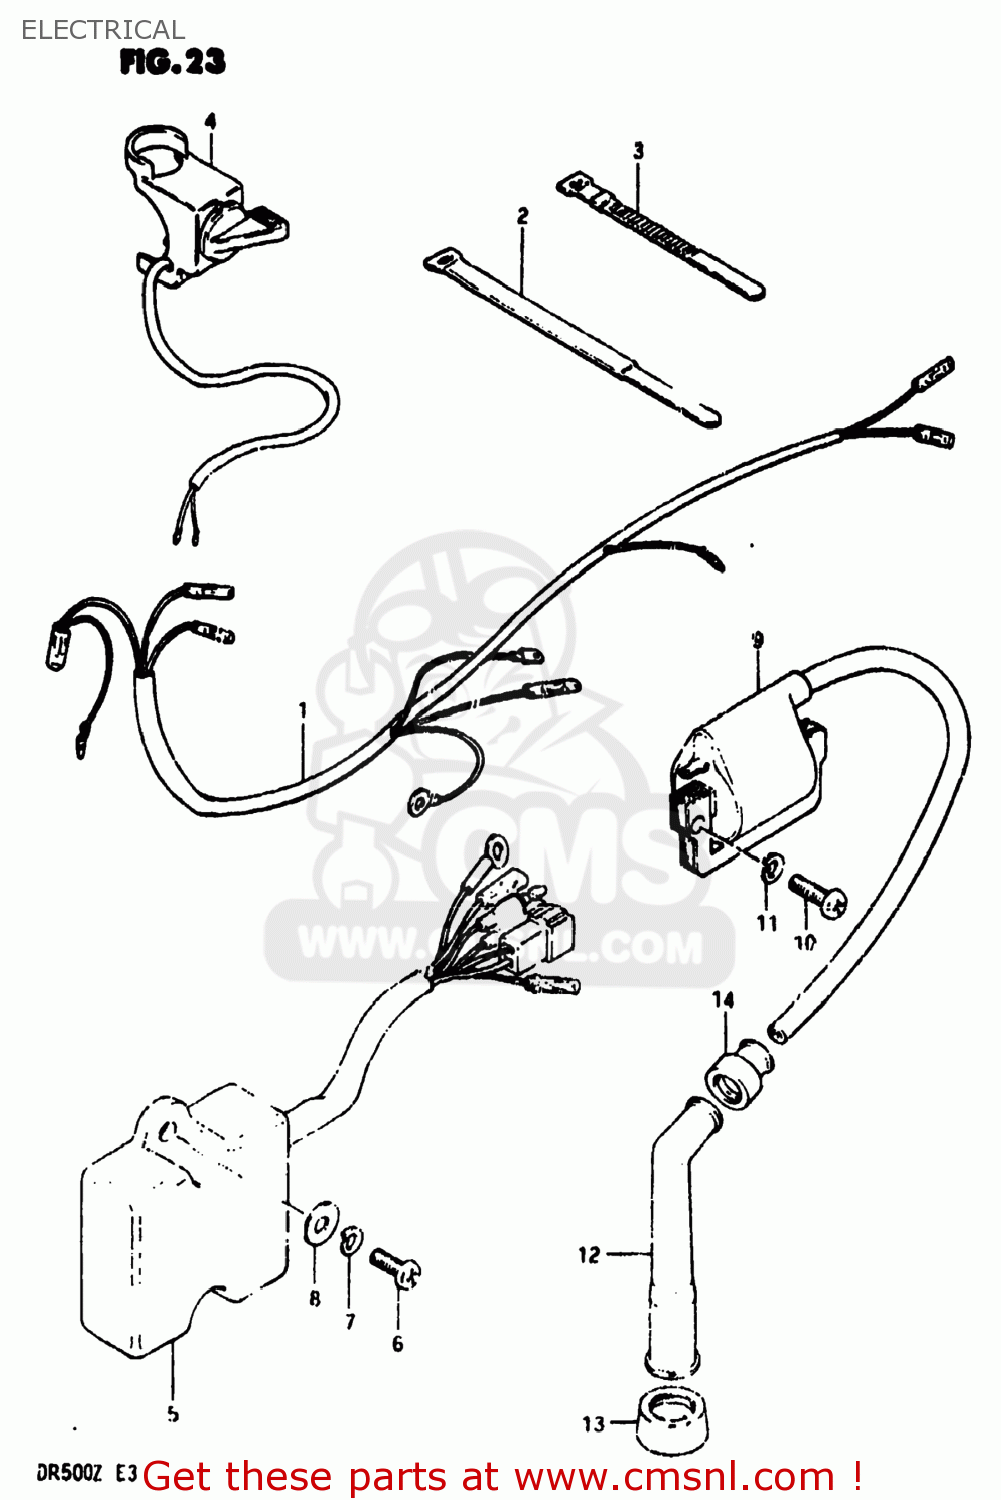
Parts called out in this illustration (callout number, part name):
1	HARNESS,WIRING
2	CLAMP
3	CLAMP(L:120)
4	SWITCH ASSEMBLY
5	CDI UNIT
6	SCREW
7	LOCK WASHER
8	WASHER (6.5X18X1.6)
9	COIL ASSEMBLY,IGNITION
10	SCREW
11	LOCK WASHER
12	CAP ASSY,SPARK PLUG
13	SEAL,SPARK PLUG
14	SEAL,SPARK PLU
